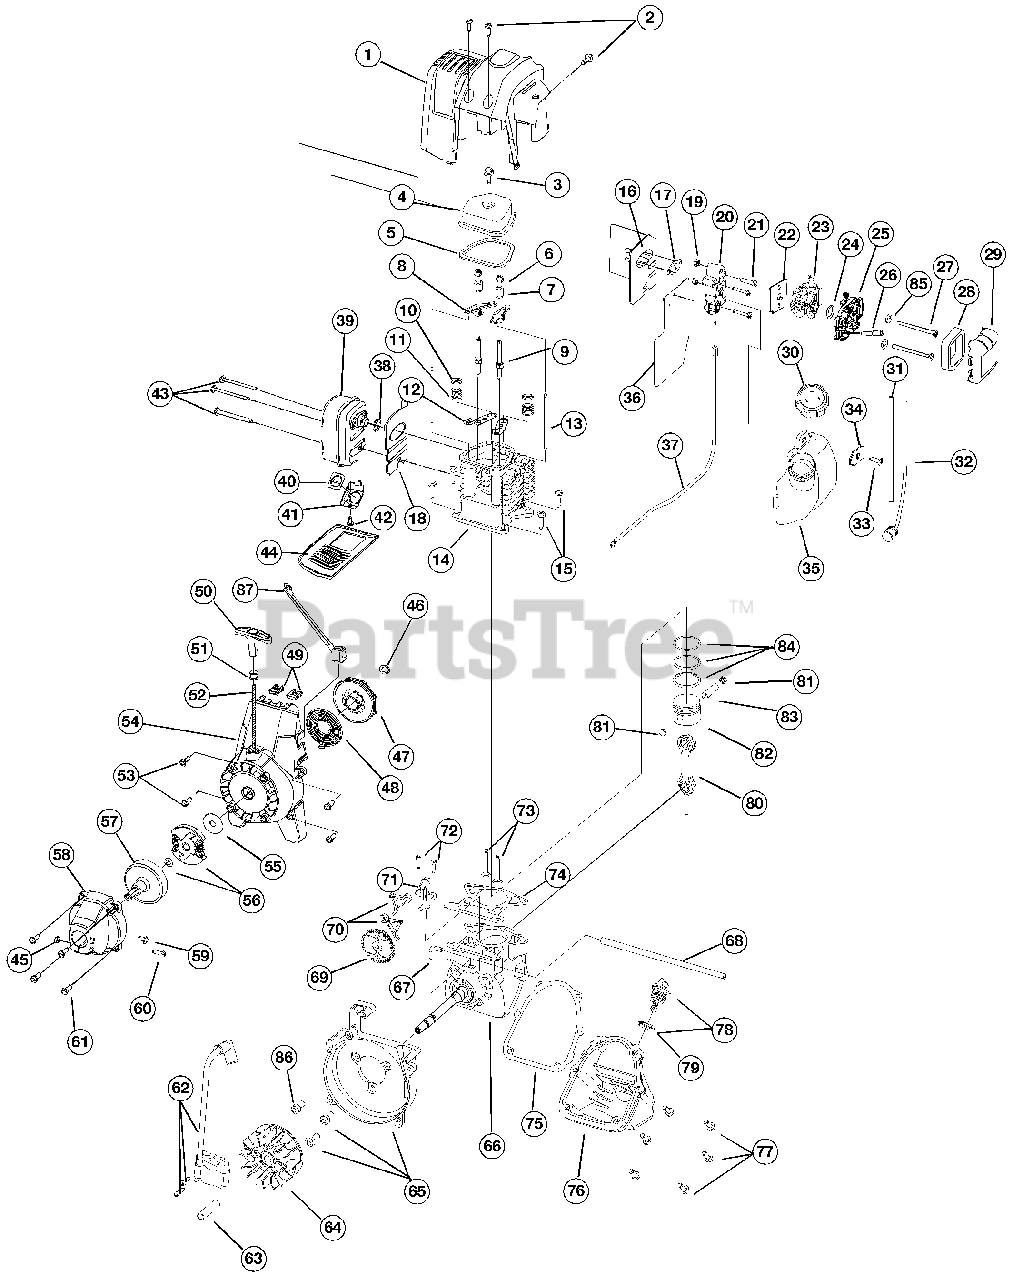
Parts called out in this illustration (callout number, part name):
1	Engine Cover
2	Engine Cover Screws
3	Valve Cover Screw
4	Valve Cover
5	Valve Cover Gasket
6	Rocker Adjustment Nut
7	Rocker Arm Pivot
8	Rocker Arm
9	Rocker Arm Stud
10	Valve Spring Retainer
11	Valve Spring
12	Push Rod Guide
13	Push Rod
14	Cylinder Head Assembly
15	Cylinder Screw
16	Intake Baffle
17	Carburetor Mount Gasket
18	Muffler Baffle
19	Nut
20	Carburetor Mount
21	Carburetor Mount Screw
22	Carburetor Gasket
23	Carburetor with Primer
24	O-Ring, Carburetor
25	Air Filter/Choke Cover Assembly
26	Breather Tube
27	Air Filter Mounting Screw
28	Air Filter
29	Air Filter Cover
30	Fuel Cap
31	Fuel Return Line
32	Fuel Pick-Up Line with Filter
35	Fuel Tank Assembly
36	Fuel Tank Shield
37	Throttle Cable
38	Muffler Gasket
39	Muffler
40	Spark Arrestor Screen
41	Screen Cover
43	Muffler Mounting Screw
44	Muffler Cover
46	Pal Nut Retaining Ring
47	Recoil Pulley
48	Recoil Spring
49	Nut Clip
50	Pull Handle
51	Rope Guide
53	Starter Housing Assembly
54	Starter Housing Screw
55	Clutch Washer
56	Clutch with Spacer
57	Clutch Drum
58	Clutch Cover
59	Anti-Rotation Screw
60	Screw
61	Clutch Cover Screw
62	Ignition Module with Screws
64	Flywheel
65	Shroud Assembly with Screws
66	Crankcase Assembly
67	90° Elbow
68	Breather Hose
69	Cam Gear
70	Cam Follower
71	Cam Bracket
72	Cam Bracket Screw
73	Valves, Intake and Exhaust
74	Cylinder Gasket
75	Oil Pan Gasket
76	Oil Pan
77	Oil Pan Screw
78	Dipstick Assembly
80	Connecting Rod
81	Wrist Pin Button
82	Piston
83	Wrist Pin
84	Piston Ring Set
87	Ignition Switch Assembly w/ Leads
